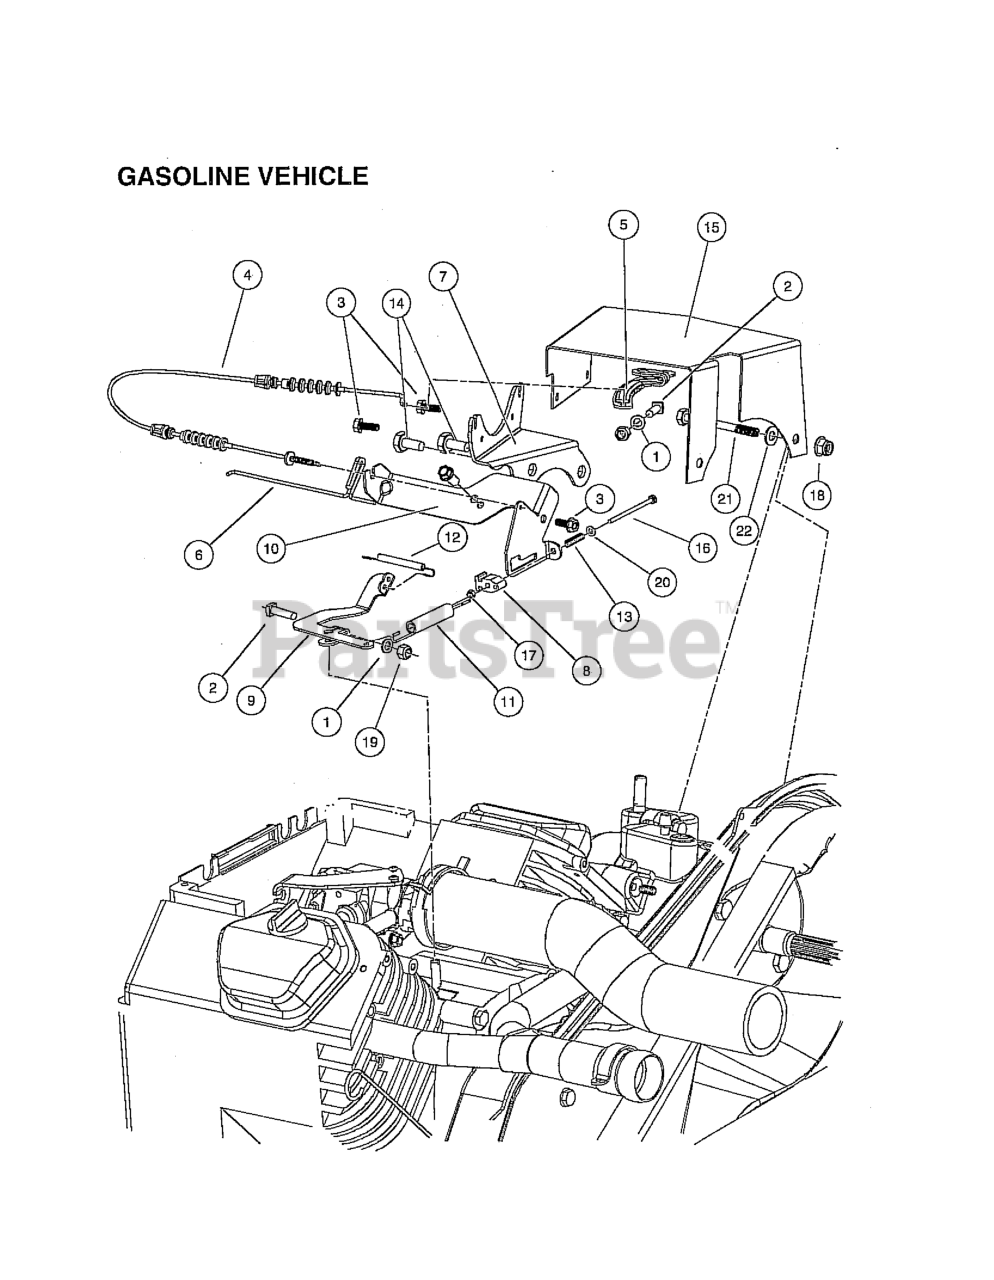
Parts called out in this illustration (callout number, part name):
2	SCREW, 1/4-20 X 1.00 SQ HEAD
3	SCREW, M6 X 16 TT HX FL HD
4	CABLE, GOVERNOR, GX620
5	BRACKET, GOVERNOR, ARM, TRANS
6	WIRE, GOVERNOR
7	BRACKET, GOVERNOR, TRANS CABLE
8	ADJUSTER, SPRING, IDLE
9	BRACKET, ARM, GOV, ENGINE
10	BRACKET, CABLE, GOV, ENGINE
11	SPRING, IDLE , GOVERNOR
12	SPRING, CARB
13	SPRING, COMPRESSION, ADJ, IDLE
14	BOLT, M10 X 1.5 X 20 LOCTITE
15	GUARD, GOVERNOR, GROUND SPEED
16	BOLT, M4X.7X60
17	NUT FLG, M4 X 0.7 MECH DEF
18	LOCK NUT, FLG M8 X 1.25 NYLON
19	LOCKNUT, 1/4-20 NYLON INSERT
20	WASHER, M4
21	BOLT, M8 X 1.25 X 80
22	WASHER, M8 HARD
